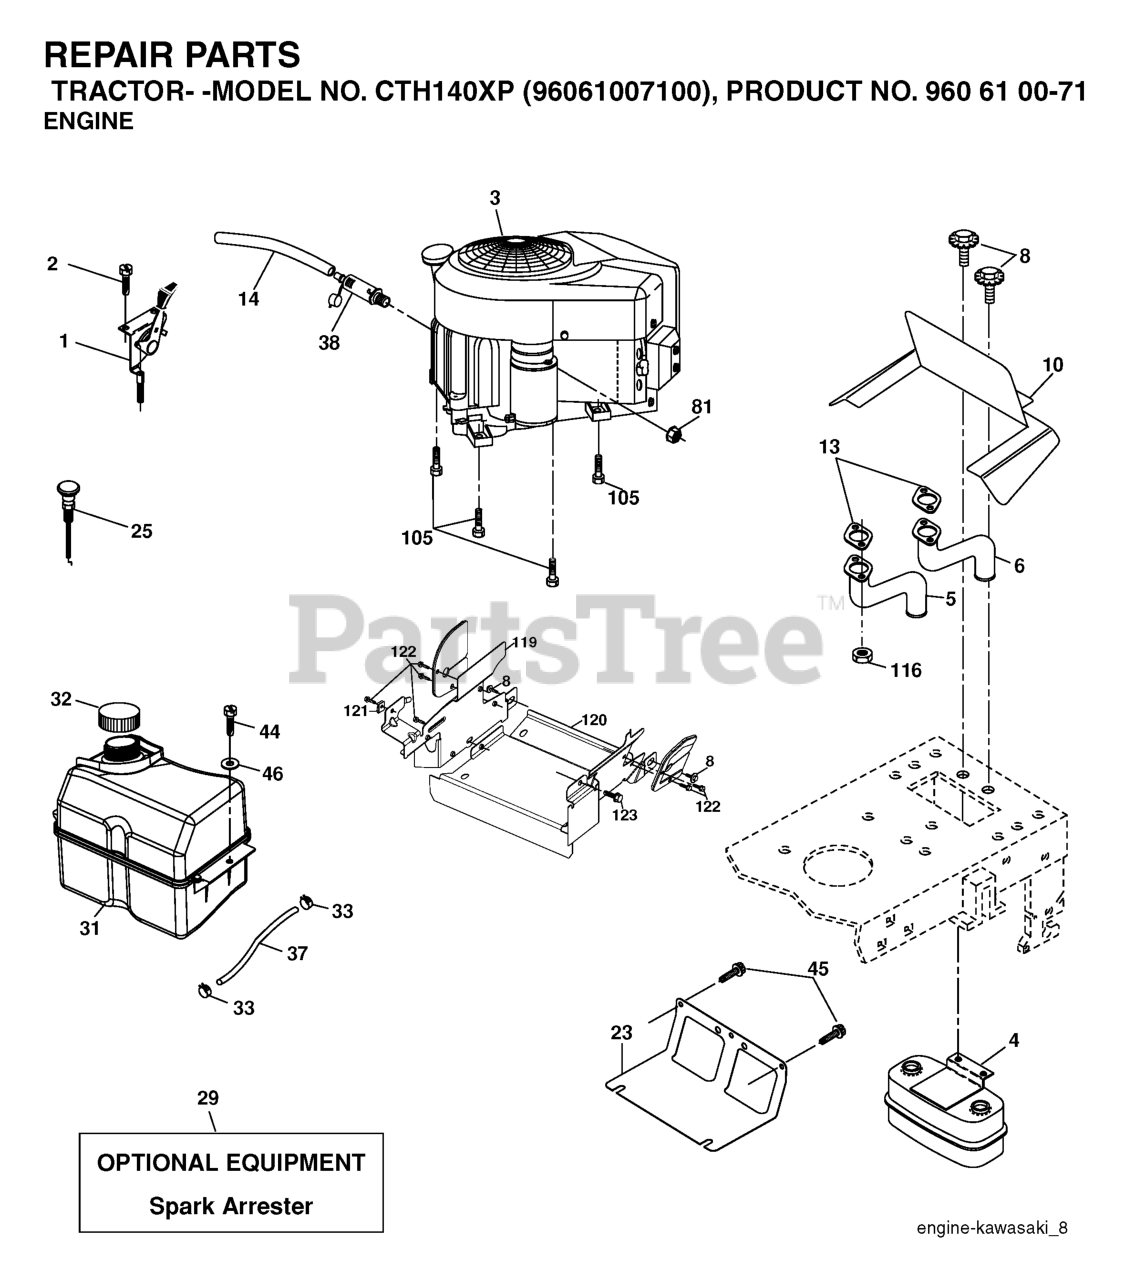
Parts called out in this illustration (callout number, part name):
1	CONTROL, THROTTLE
2	SCREW
4	MUFFLER.TWIN.CYL.LOW.TONE
5	EXHAUST TUBE LH KAWI
6	EXHAUST TUBE RH KAWI
8	BOLT.5/16-18UNCX3/4 W/SEMS.BLK
10	RP SHIELD HEAT MUFFLER
14	TUBE, DRAIN OIL ASM.
23	SHIELD.BROWNING.DBR.GUARD
29	KIT.SPARK ARRESTOR 794945 B&S
31	TANK FUEL
32	FUEL CAP
33	HOSE CLAMP
37	LINE.FUEL.20
44	SCREW HEXWSHR 1/4-20X3/4
45	SCREW, 3/8-16X3/4
46	WASHER
81	NUT
105	SCREW 3/8-16X1
116	NUT.HEX.FLANGE.TOPLOCK
122	SCREW.1/4-20X5/8
123	SCREW, 5/16-18 X 1/2
